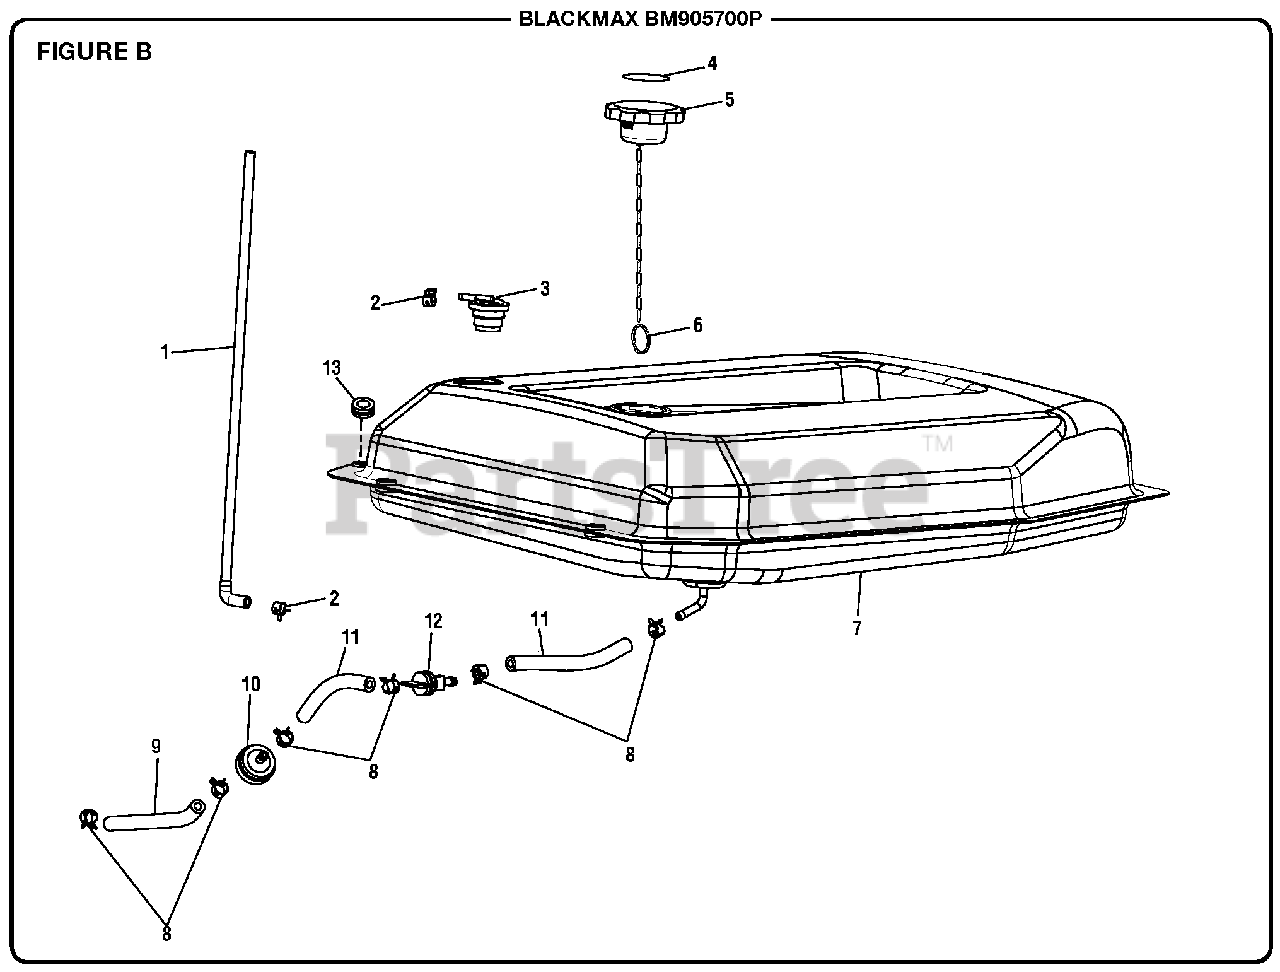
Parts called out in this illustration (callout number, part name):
1	Vapor Hose
2	Clamp (7/16 in.)
3	Fuel Tank Vapor Vent
4	Fuel Stabilizer Label
6	Ring Clip
7	Fuel Tank
8	Clamp (1/2 in.)
9	Fuel Hose
10	Fuel Filter
11	Fuel Hose
12	Fuel Shut Off Valve
